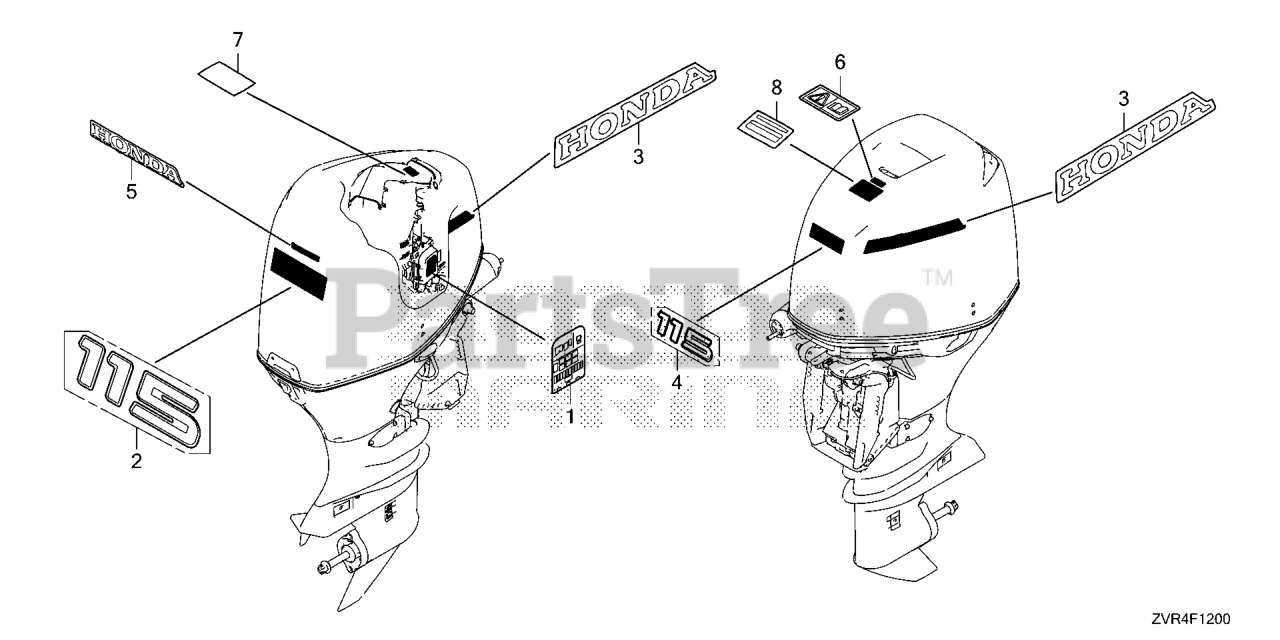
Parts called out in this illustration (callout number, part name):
1	LABEL, FUSE
2	MARK, RR. (115)
3	MARK, SI (STRIPE150)
4	MARK, FR. (115)
5	MARK, HONDA
7	LABEL, CAUTION OIL
8	LABEL, WARNING OPERATOR (ENGLISH)
